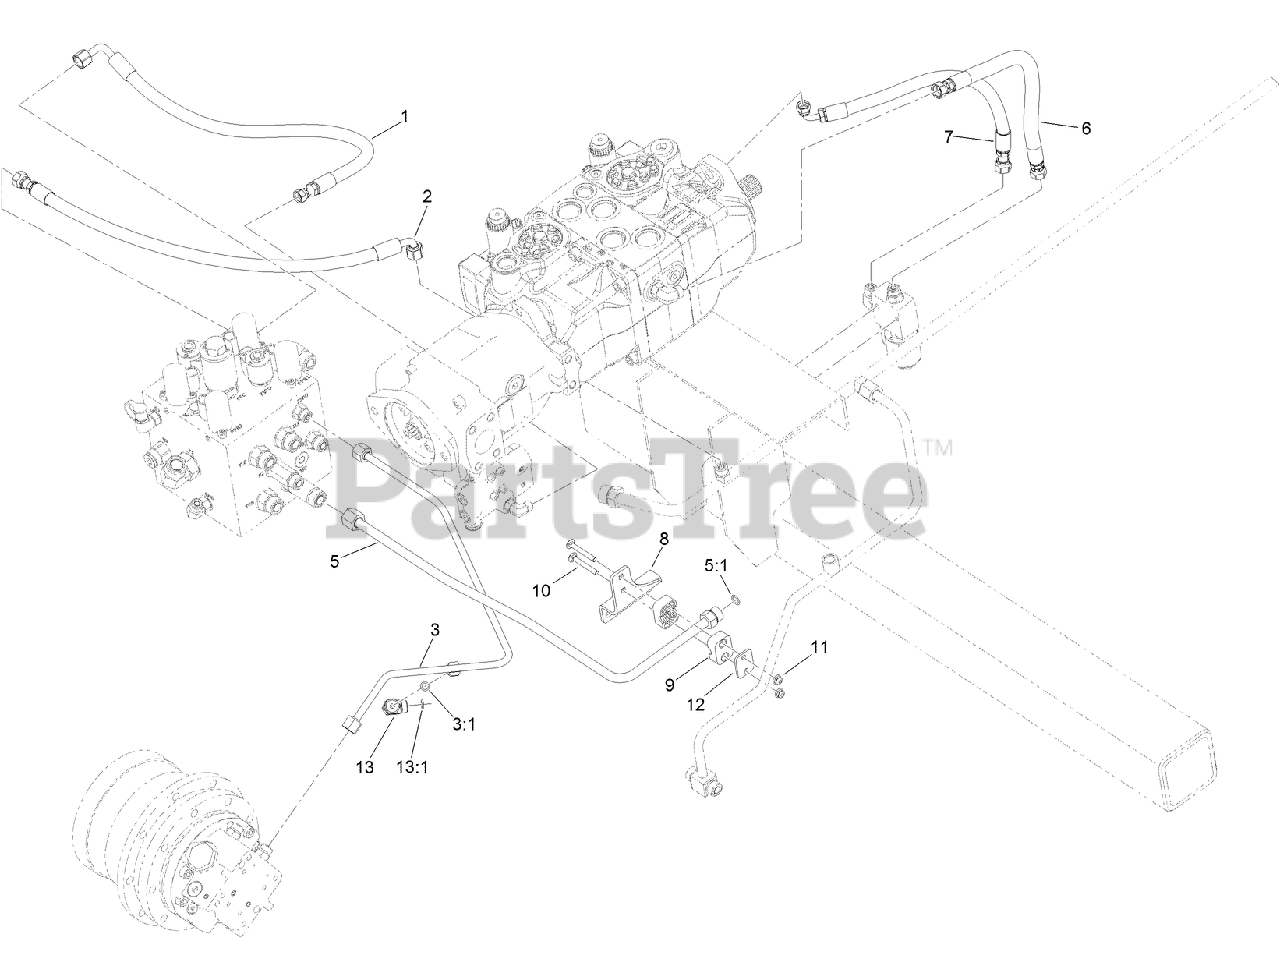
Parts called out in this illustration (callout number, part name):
1	HOSE-HYD
2	HOSE-HYD
3	HYD TUBE ASM
3:1	O-RING
5	HYD TUBE ASM
5:1	O-RING
6	HOSE-HYD
7	HOSE-HYD
8	BRACKET-CLAMP, STAKE DOWN
9	CLAMP-TUBE
10	SCREW-CARR
11	NUT-HF
12	PLATE-COVER, CLAMP
13	FITTING-HYD, 90 DEG
13:1	O-RING
